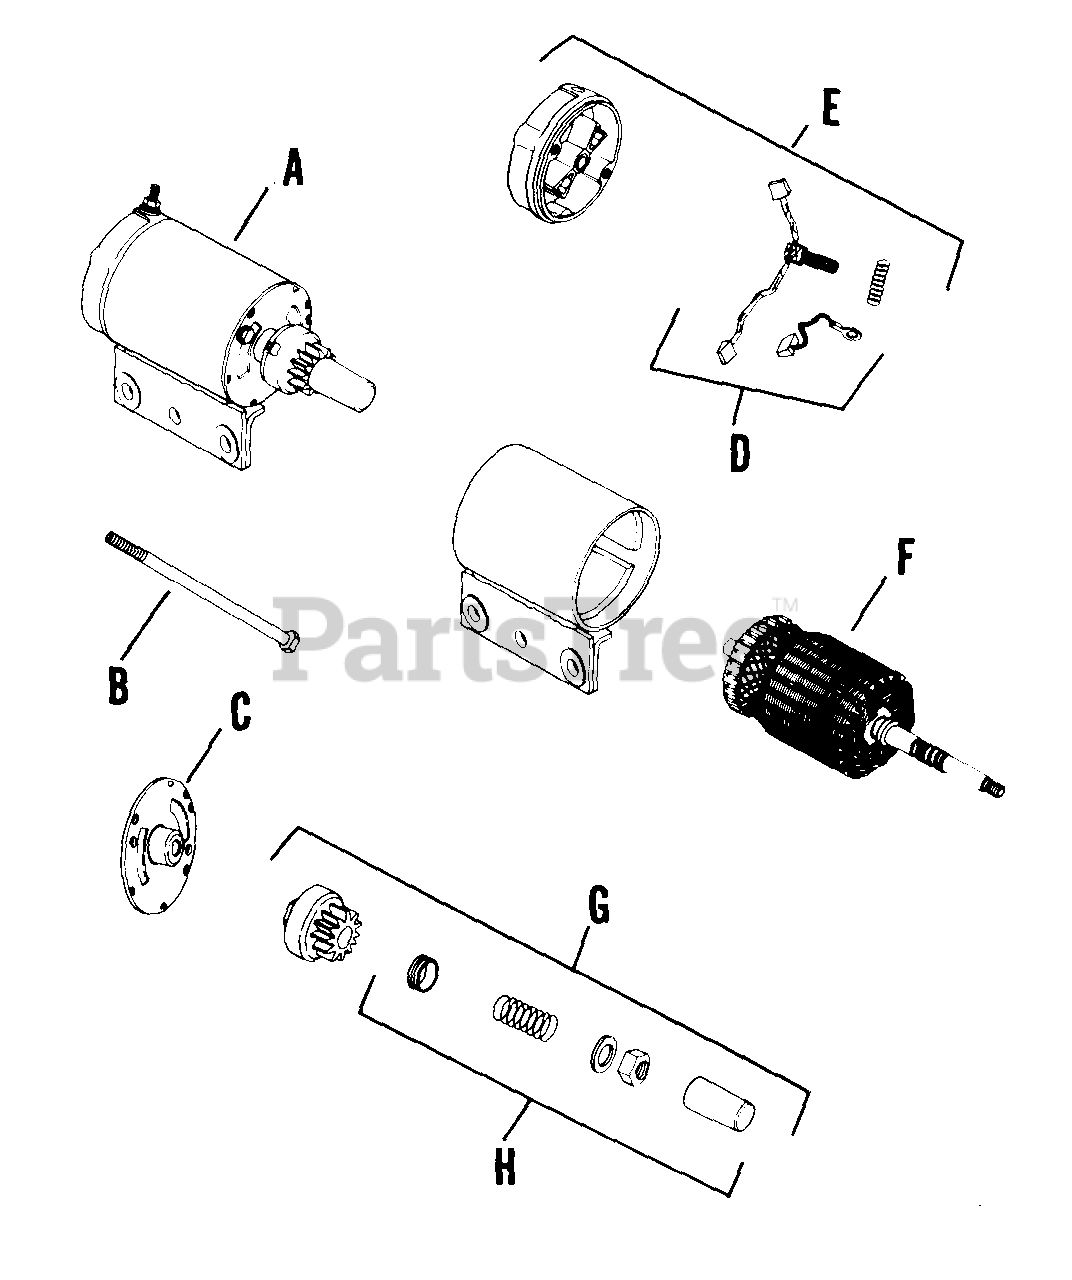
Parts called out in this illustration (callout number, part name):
A	STARTER - USE 45 098 11
C	CAP - USE 45 081 05
D	KIT - USE 52 755 15
E	CAP - DISCONTINUED
F	ARMATURE - DISCONTINUED
G	KIT - USE 47 749 02
